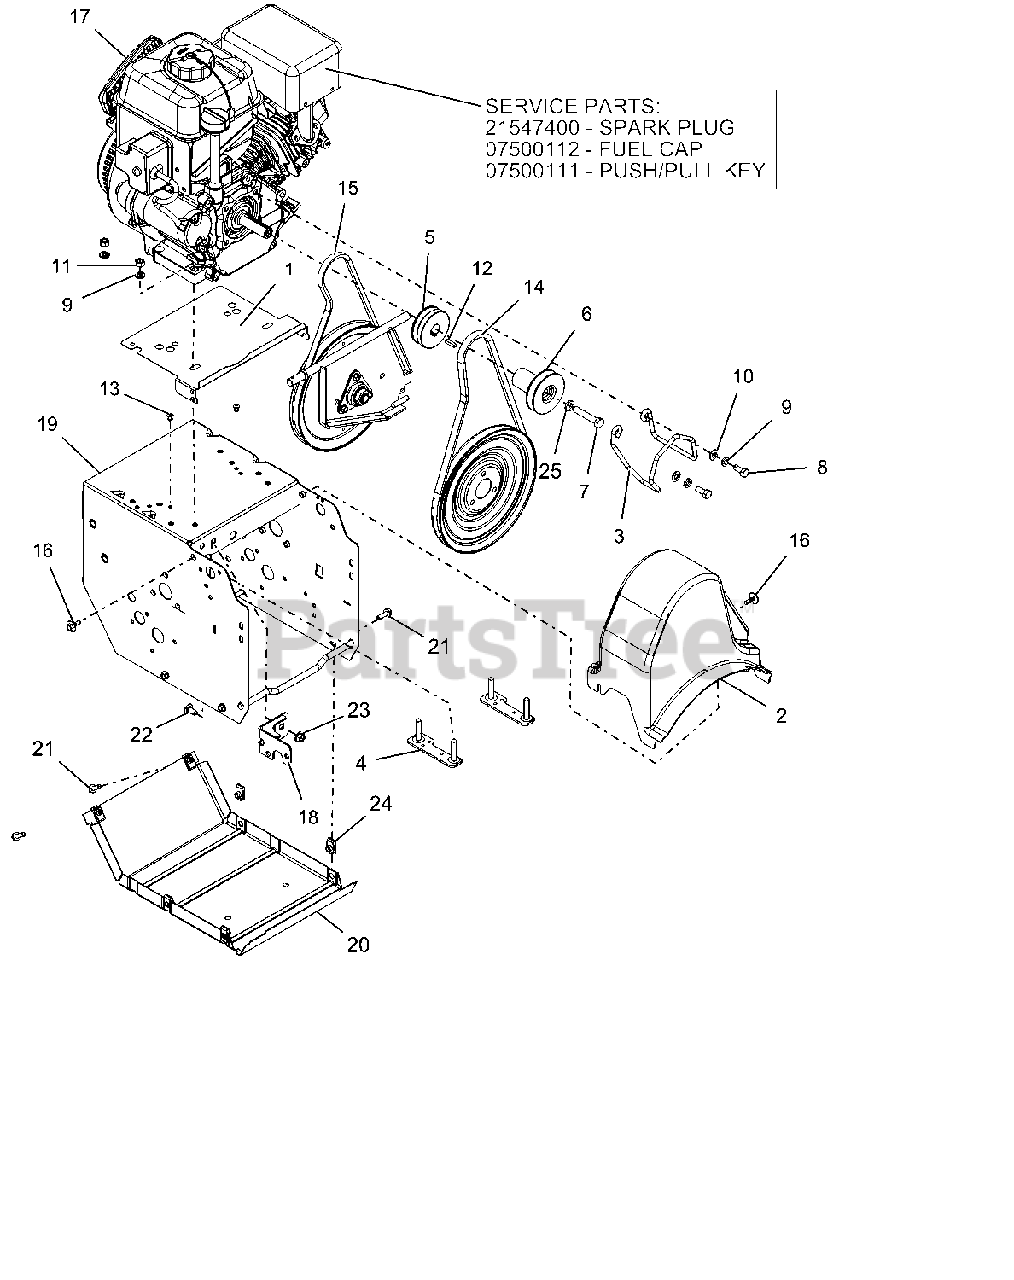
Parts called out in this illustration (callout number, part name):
1	BAFFLE,ENGINE,SMALL BLOCK
2	COVER, COMPACT BELT
3	FINGER, BELT
4	STRAP, ENGINE BOLT-WELDMENT
5	SHEAVE, TRACTION-COMPACT TRACK
6	SHEAVE,AUGER 3/4" PM
7	BLT-HEX .38-24X2.0 YWZC
8	BLT-HEX .31-24X.75 YWZC GR5
9	WSHR-LK .312X.097 HVY YWZC
10	@WSHR-FL-STL.344X.688X.065YWZC
11	@NUT-HEX .31-18 YWZC
12	KEY-SQ .188X.75X.188
13	RVT-POP .187 YZ
14	V-BELT, HA-RAW EDGE
15	V-BELT, 3L-WRAPPED
16	SCR-TAP .25-20X.5 CAPTIVE
17	ENGINE, AX208 GEN 2 120V/60W
18	WELDMENT, FRAME BRACKET
19	FRAME, 920/921
20	COVER, BOTTOM
21	BLT-HEX .25-20X.75 HWH YZ GR5
22	@BLT-RHDSSQNK .31-18X.62 G5YZ
23	@NUT-LK-TOP-FLG .31-18 YWZC
24	NUT-RTNR .25-20X.56
25	WSHR-LK .375X.115 HVY YWZC
26	PLUG, SPARK
27	CAP, FUEL TANK BLACK
28	KEY, PUSH/PULL LCT (2/PACKAGE)
